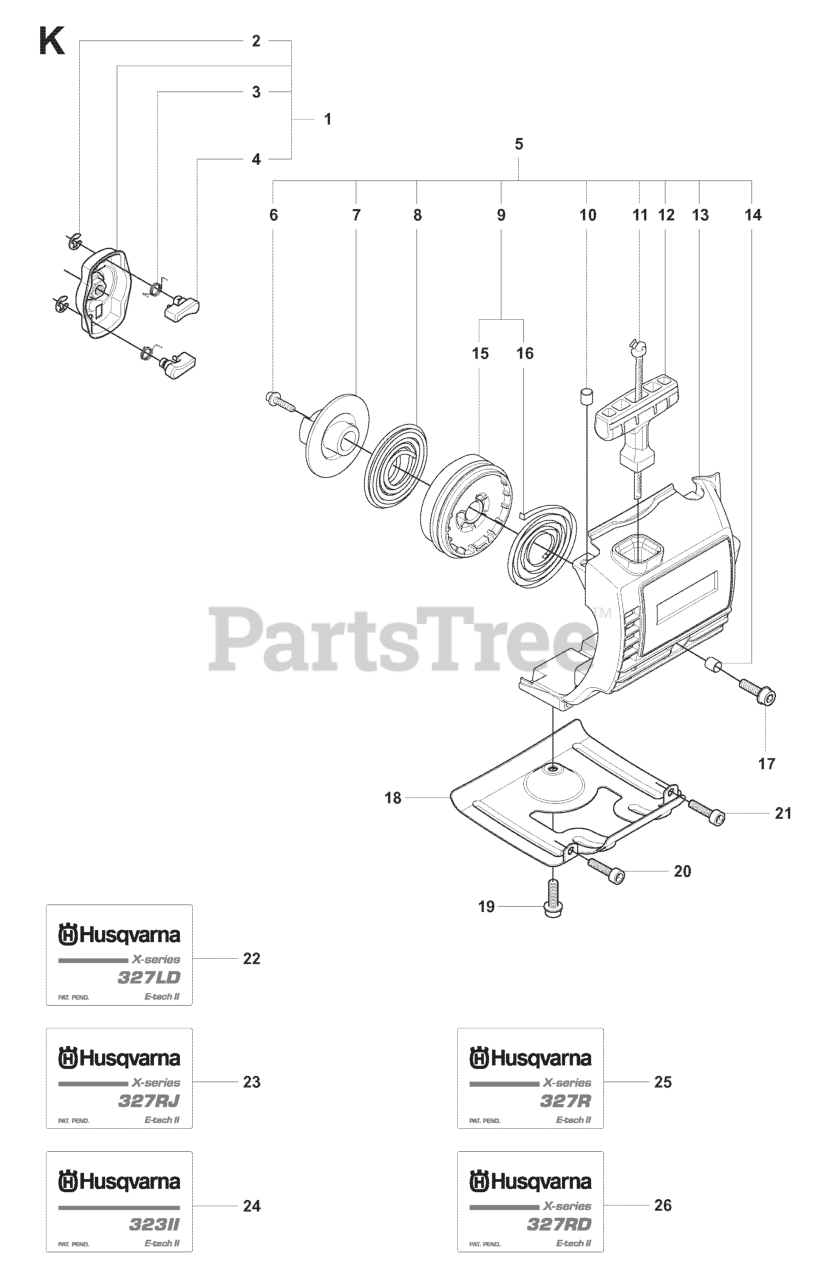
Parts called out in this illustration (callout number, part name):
1	STARTER PAWL BRIDGE
4	STARTER PAWL
5	RP STARTER ASSY
7	WHEEL
8	BALANCING SPRING
9	STARTER PULLEY
10	SPACING SLEEVE
11	STARTER ROPE
12	STARTER HANDLE
13	RP STARTER HOUSING
14	SPACING SLEEVE
15	STARTER PULLEY
22	LABEL 327LDX
23	LABEL 327RJ
24	LABEL 323 RII
25	LABEL 327RX
26	LABEL 327RDX
